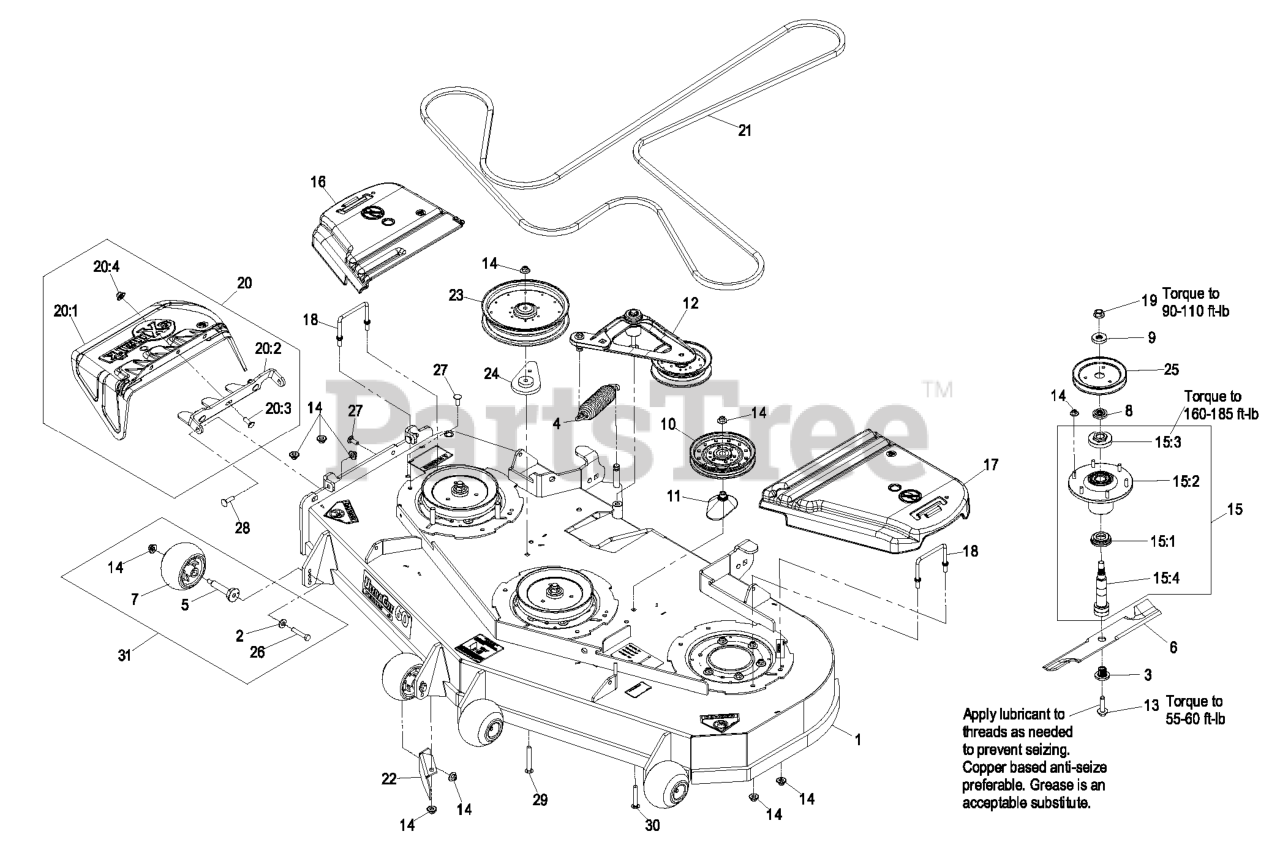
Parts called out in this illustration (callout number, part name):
2	WASHER-BELLEVILLE
3	BUSHING,SPLINED
7	ROLLER-SCALP, ANTI
8	SPACER,SPLINED STEPPED
9	SPACER,SPLINED
11	SPACER-PULLEY
13	SCREW,SEMS 1/2-20 X 2.19
14	Nut-Nyloc 3/8-16 Flg
15	ASM,SPINDLE HOUSING
15:1	GUARD,BOTTOM
15:2	ASM,CUTTER HOUSING
15:3	NUT, SPINDLE 7/8-14
15:4	SPINDLE,DOUBLE SPLINE
16	COVER-BELT, RH
17	COVER-BELT, LH
18	WIREFORM-COVER
19	NUT-FLANGE, CENTERLOCK
20	ASM,DISCHARGE CHUTE
20:1	CHUTE,DISCHARGE
20:2	BRACKET,DISCHARGE CHUTE
20:3	SCREW-CARR
20:4	Nut-Nyloc 3/8-16 Flg
21	BELT,V-5V-198.75
22	BAFFLE,DISCHARGE 52/60
23	PULLEY-IDLER
24	SPACER-IDLER
25	SHEAVE,BLADE DRIVE 7.25
26	SCREW-HH
27	SCREW-CARR
28	Bolt-Carriage 3/8-16 X 1 1/4
29	SCREW-CARR
30	SCREW-CARR
32	Asm, Deck Complete 606
